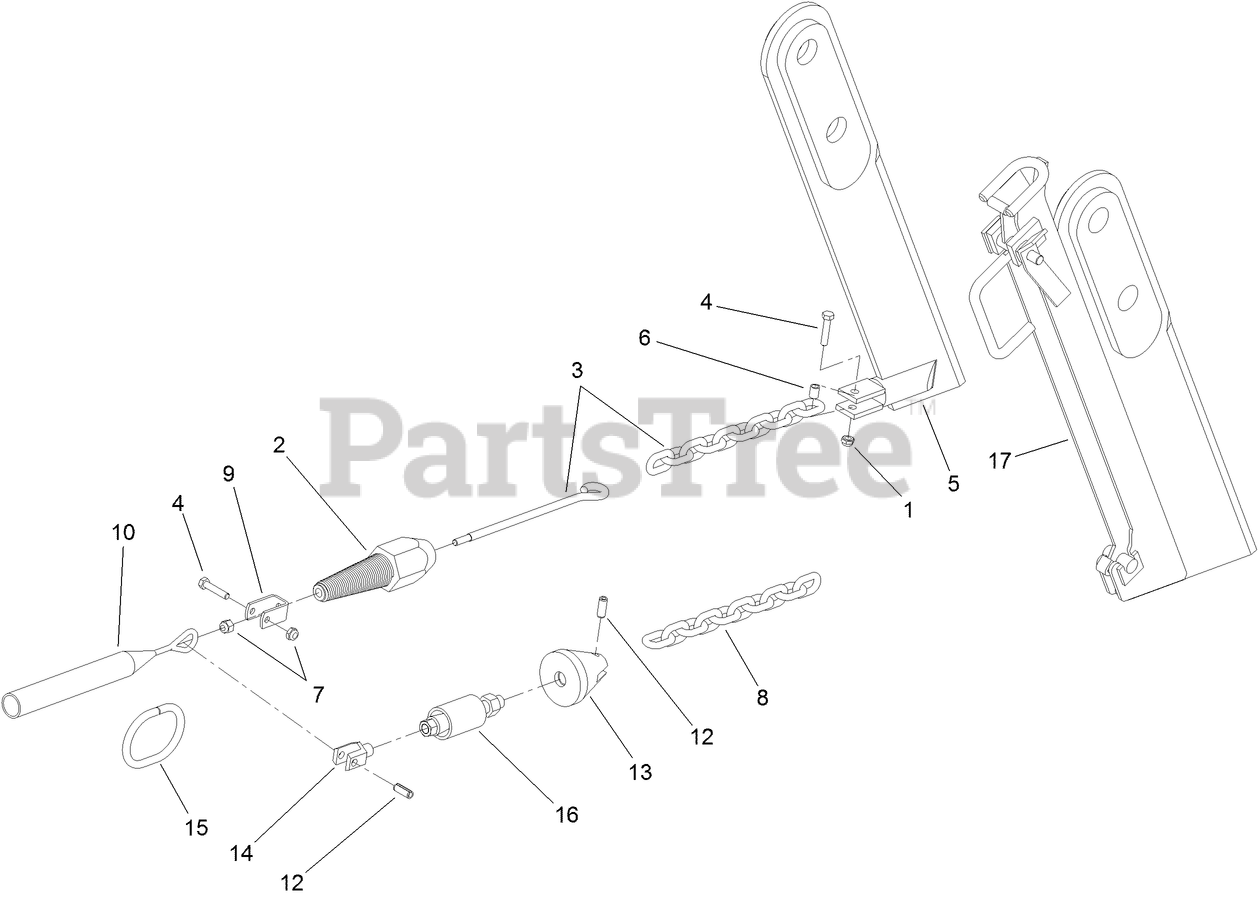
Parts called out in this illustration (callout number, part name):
1	NUT-LOCK, NI
2	PULLER-PIPE
3	CHAIN ASM
4	SCREW-HH
5	PLOW BLADE ASM (.38 X 12)
5	PLOW BLADE ASM (.25 X 12)
5	PLOW BLADE ASM (.5 X 18)
5	PLOW BLADE ASM (.38 X 18)
6	SPACER
7	NUT-LOCK, NI
8	CHAIN
9	CLEVIS
10	BASKET-GRIP (1.25-1.5)
10	BASKET-GRIP (.75-1.25)
12	PIN-ROLL
13	BULLET-PULLER
14	ADAPTER-CHAIN
15	LINK-WIRE
16	PULLER ASM (1 INCH)
16	PULLER ASM (2 INCH)
16	PULLER ASM (1.5 INCH)
17	CHUTED BLADE ASM
